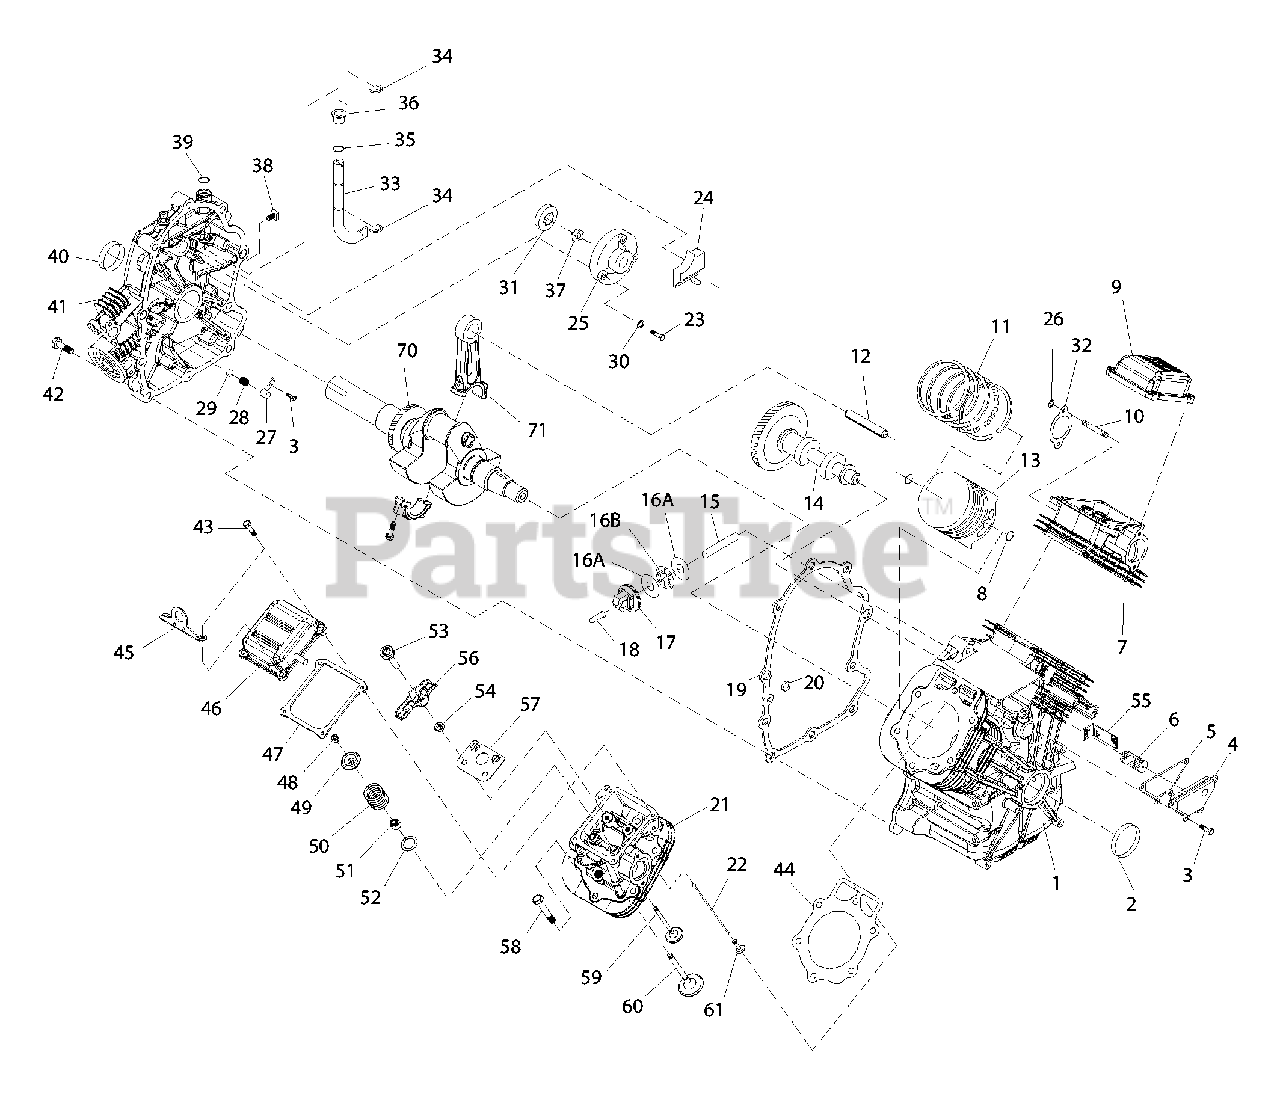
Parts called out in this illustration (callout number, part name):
1	ASSY,CRANKCASE VS W/SLEEVE
2	SEAL, 38 I.D. CRANKSHAFT
3	SCREW, TAPTITE M6-1.0 X 12 YC
4	ASSEMBLY, BREATHER
5	GASKET, BREATHER COVER
6	SEPARATOR, OIL BREATHER
8	RETAINER, PISTON PIN 20
9	ROCKER, COVER NO OIL FILL
10	STUD M8-1.25/10MM X 30 G5 ZINC
11	SET, PISTON RING 90MM
12	PIN PISTON 20 DIA
13	PISTON, 9.5:1 90MM DIA (HIGH COMP.)
14	ASSEMBLY, CAMSHAFT & GEAR
15	SHAFT, GOVERNOR
19	GASKET, CRANK CASE
20	SEAL, OIL PASSAGE
22	PUSHROD, 147
23	SCREW SHC M6-1.0 X 30 G8.8
24	SCREEN, OIL PICKUP
25	COVER, GEROTOR
26	NUT LOCK FL M8-1.25
30	WASHER, LOCK RIB M6
31	GEROTOR, OUTER
32	GASKET, EXHAUST
33	ARM, GOVERNOR
34	E-RING, GOVERNOR ARM
35	THRUST WASHER, GOVERNOR
36	BUSHING, GOVERNOR LOWER
37	GEROTOR, INNER
38	PLUG, DRAIN
39	SEAL, GOVERNOR SHAFT
40	SEAL, 42 I.D. CRANKSHAFT
41	ASSEMBLY, SUMP WITH SLEEVE
42	SCREW, HHFC M10-1.5 X 55
43	SCREW HHFC M6-1.0 X 25
44	GASKET, HEAD
45	HOOK, LIFTING
46	ASSEMBLY, ROCKER COVER W/
47	GASKET, VALVE COVER
48	KEEPER, VALVE SPRING
49	RETAINER, VALVE SPRING
50	SPRING, VALVE
51	SEAL, VALVE STEM D7
52	WASHER, VALVE SPRING
53	STUD, ROCKER ARM PIVOT
54	NUT, HEX M8-1.0 G8 YEL CHR
55	SCREEN C'CASE BREATHER
56	ROCKER ARM
57	PLATE, PUSH ROD GUIDE
58	SCREW HHFC M8-1.25 X 65
59	VALVE, EXHAUST
60	VALVE, INTAKE
61	TAPPET, SOLID
70	ASSY,C'SHFT & GEAR 100MM
71	CON ROD
